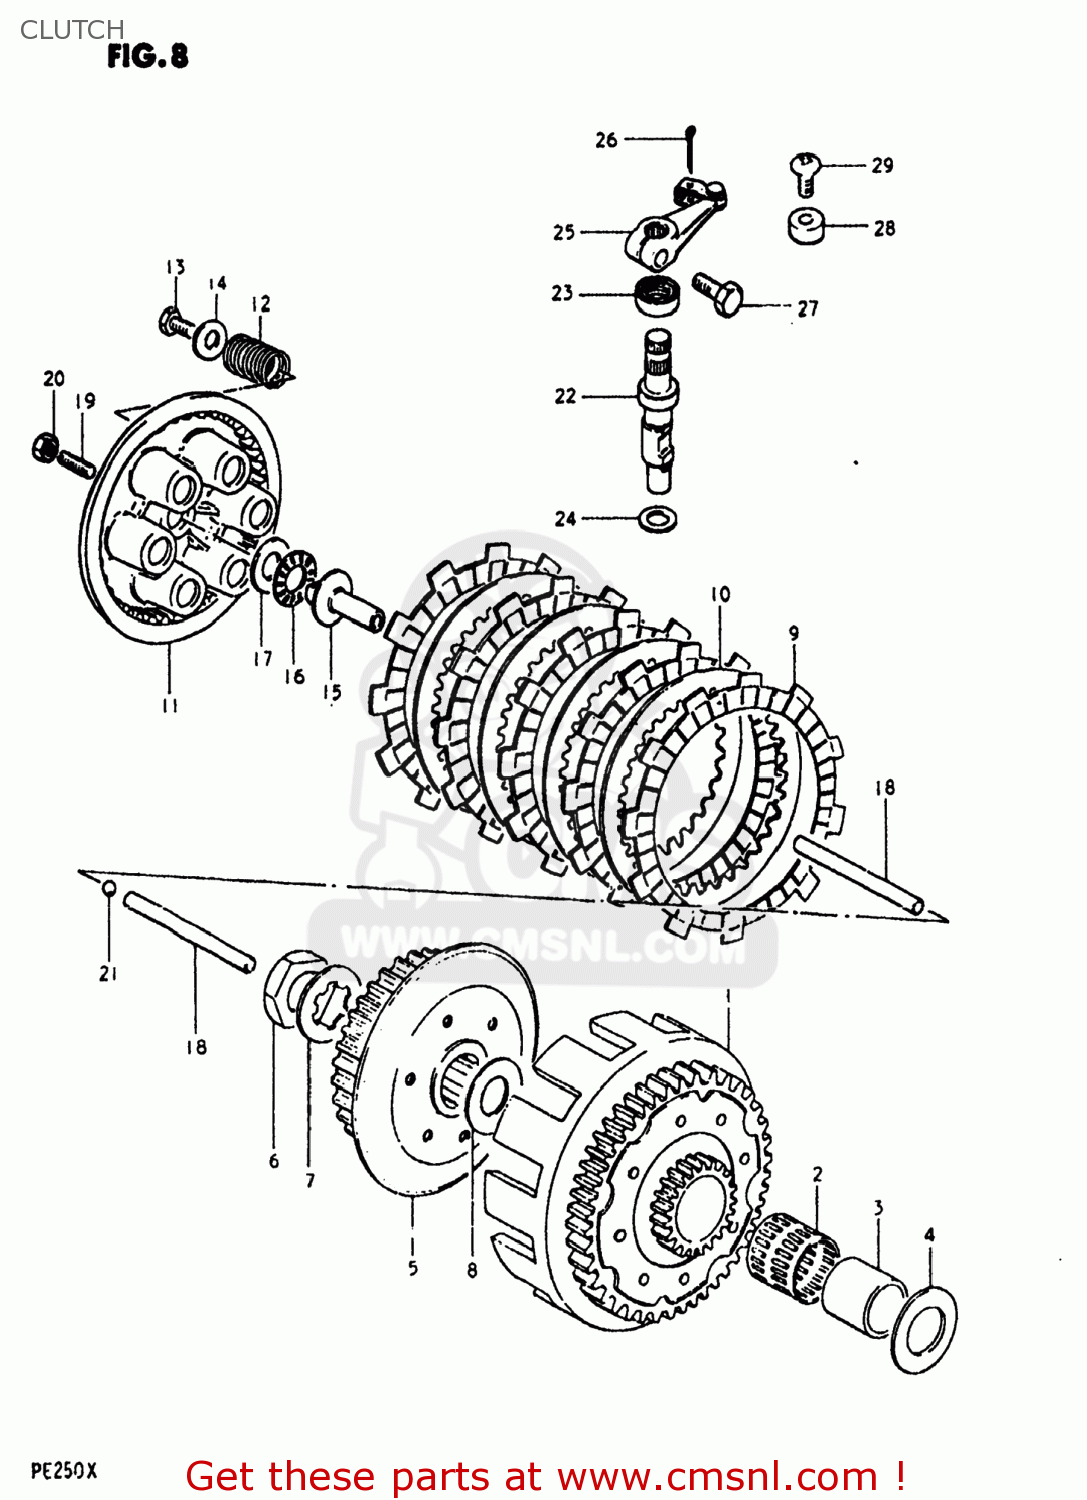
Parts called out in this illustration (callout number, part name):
1	GEAR ASSEMBLY,PRIMARY DRIVE
2	ROLLER BEARING (25X30X2
3	SPACER
4	WASHER(20X38X2)
5	HUB,CLUTCH SLEEVE
6	NUT (20MM)
7	WASHER,LOCK
8	WASHER(20X38X2)
9	PLATE,CLUTCH DRIVE (MCA)
10	PLATE,CLUTCH DRIVEN(T:2.0) (NAS)
11	DISC,CLUTCH PRESSURE
12	SPRING
13	BOLT, UPPER
14	WASHER
15	PIECE,CLUTCH PUSH
16	BEARING(15X28X2)
17	WASHER
18	ROD,CLUTCH PUSH
19	SCREW
20	NUT 6MM
21	BALL
22	SHAFT,CLUTCH RELEASE C
23	OIL SEAL
24	WASHER (14.2X22X1)
25	ARM,CLUTCH RELEASE
26	PIN
27	BOLT
28	GUIDE,CLUTCH CABLE
29	SCREW
